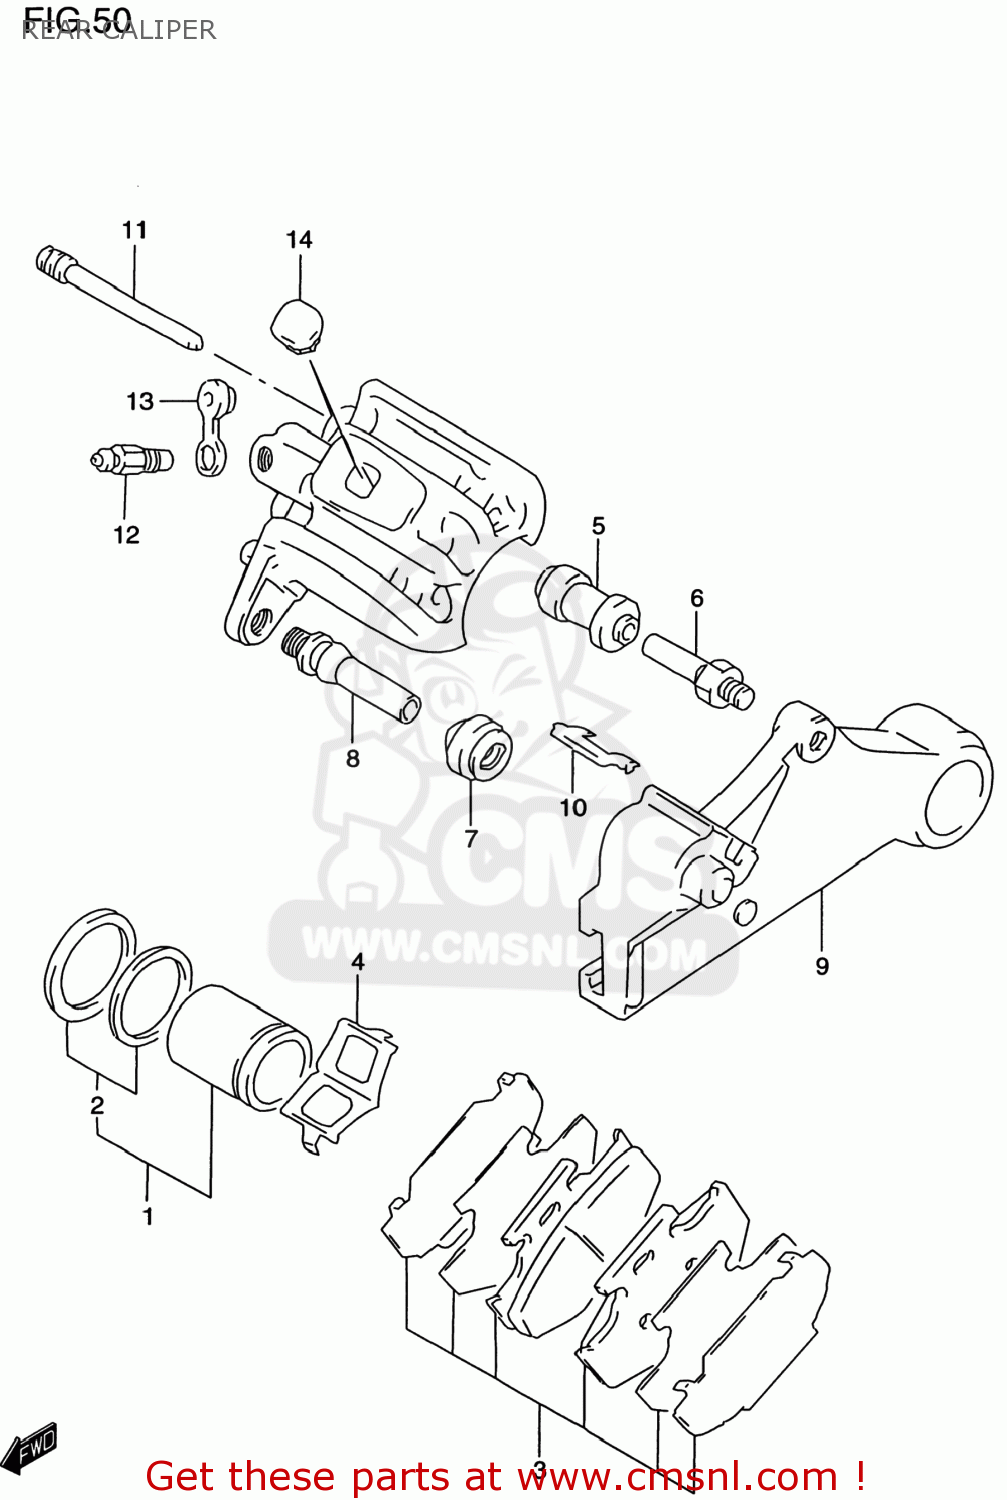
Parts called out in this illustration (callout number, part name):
1	PISTON SET
2	SEAL SET,PISTON
3	PAD & SHIM SET (NAS)
4	SPRING,PAD
5	BOOT
6	BOLT
7	BOOT
8	PIN
9	BRACKET
10	RETAINER,BRACKET
11	PIN,HANGER
12	BLEEDER
13	CAP,BLEEDER
14	COVER,RR CALIPER BODY
